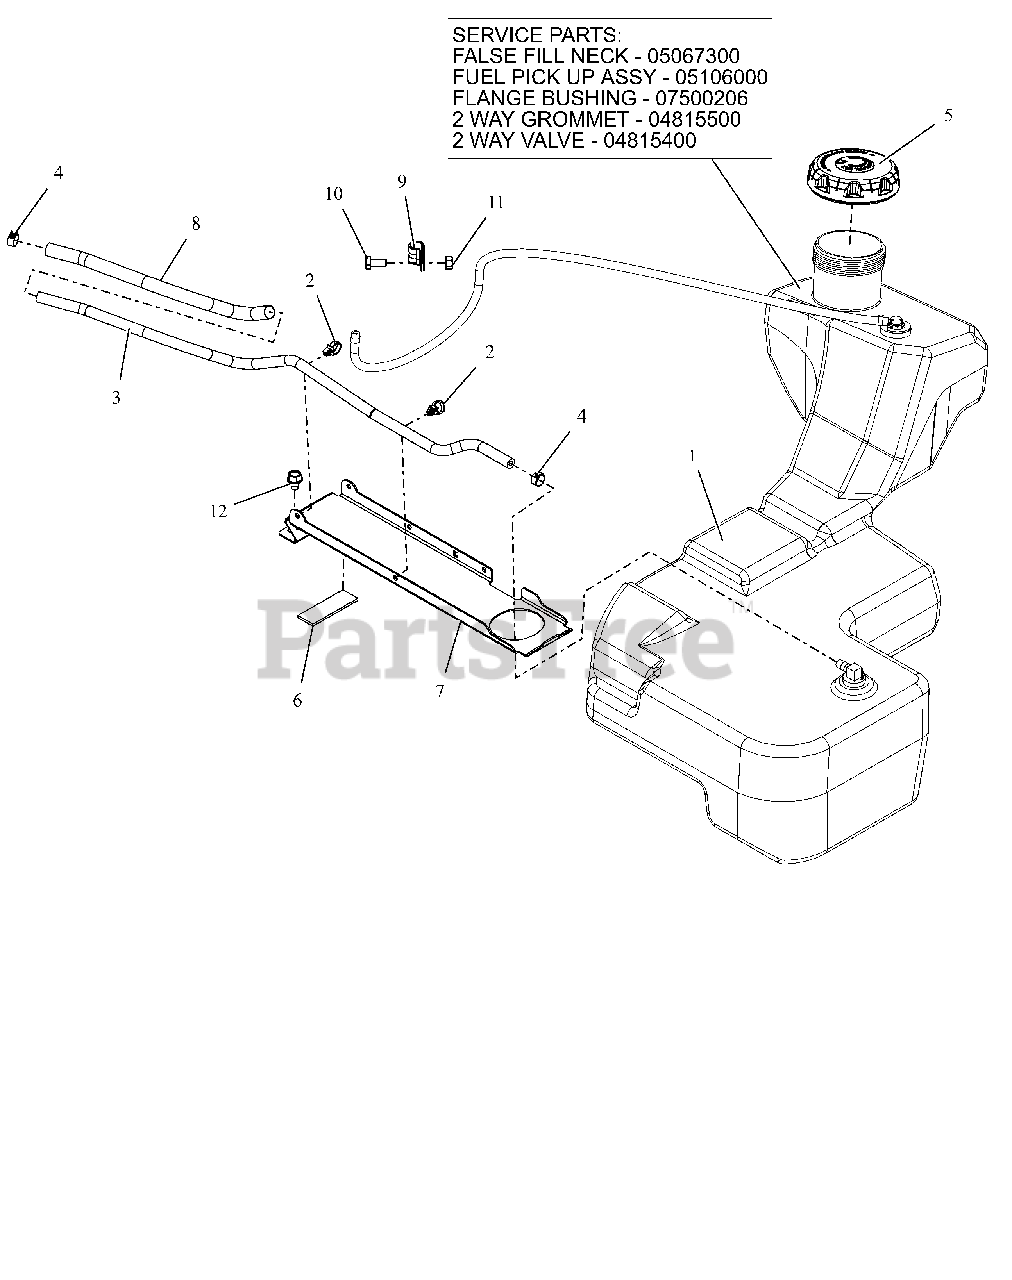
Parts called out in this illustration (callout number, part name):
1	ASM, HD FUEL TANK
1	INSERT, FUEL NECK FALSE FILL
1	ASM, HD FUEL PICK-UP
1	BSHG-FLG .375X1.062X.625 NITR
1	GROMMET, 2-WAY
1	VALVE, 2-WAY
2	ROUTING CLIP (1/2" ID)
3	HOSE, .25 LOW-PERM BULK GAS
4	CLAMP, FUEL LINE
5	CAP, FUEL VENTIN AUTOLOCK
6	PAD,RBR 1.0"X3.0" W/ADHESIVE
7	BRKT, FUEL TANK HOLD DOWN
8	SLEEVE, THERMAL 12"
9	CLAMP, CUSHIONED STEEL
10	BLT,HEX .31-18X.75 G5 ZCC
11	NUT,LK-CTR-FLG .31-18 GF ZCC
12	SCR,TAP .375-16X.50 HWH TR ZCC
